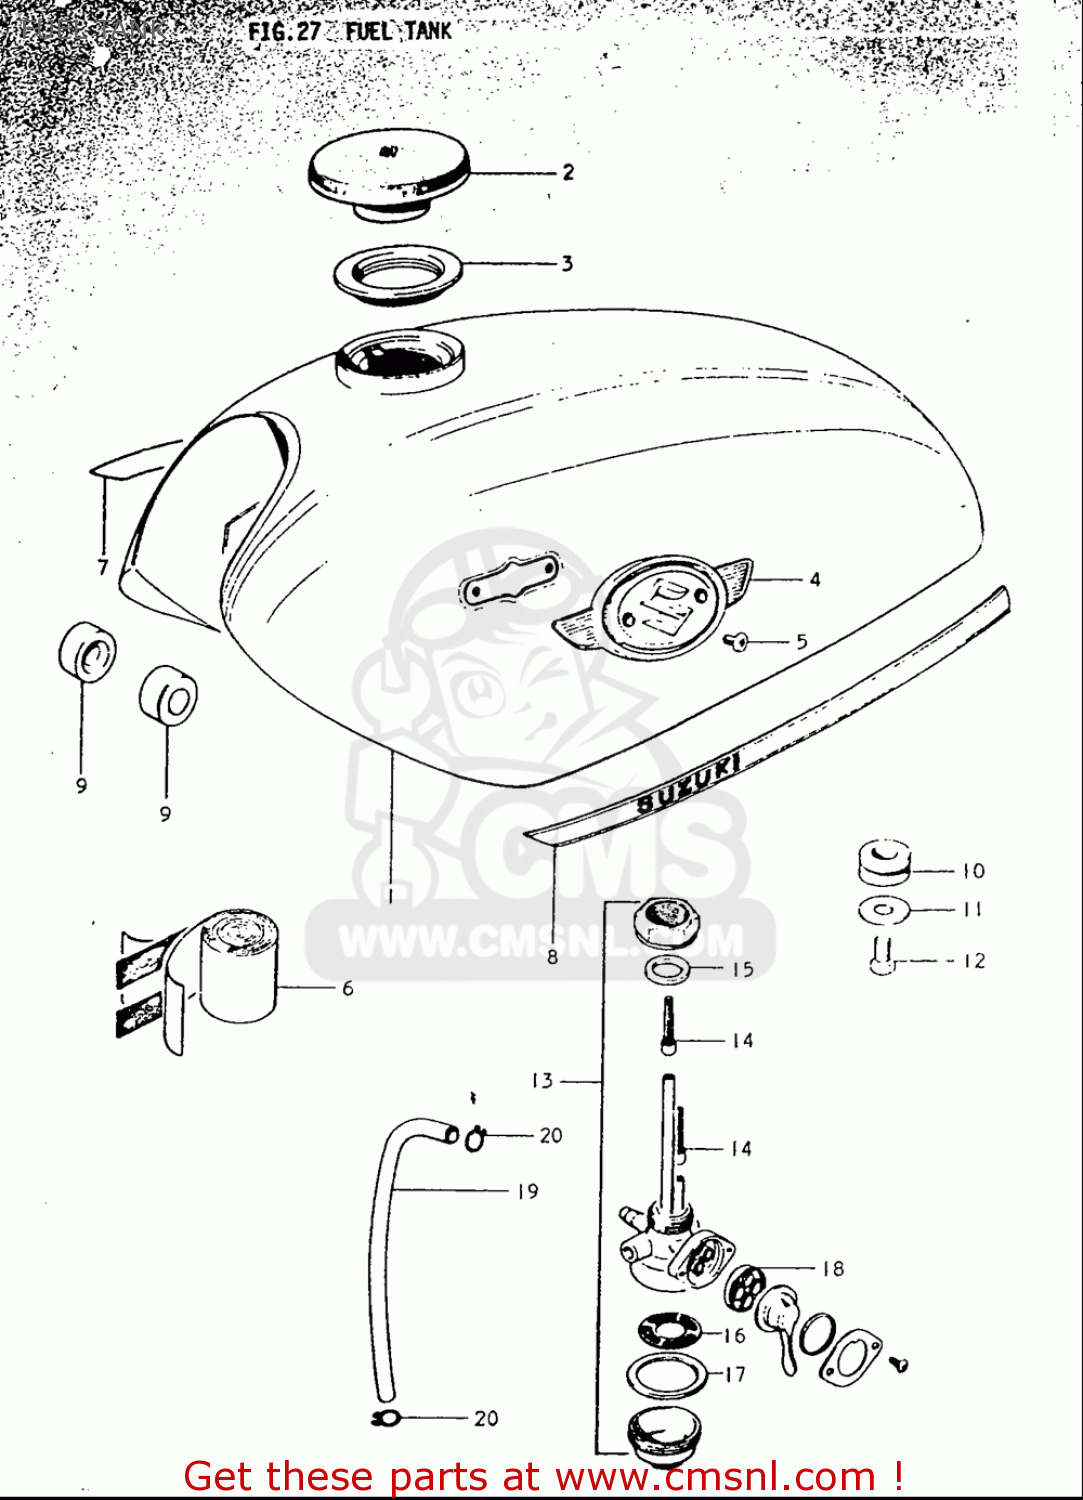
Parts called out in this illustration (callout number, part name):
9	CUSHION
11	WASHER(8.5X28X1.6)
14	FILTER SET,FUEL COCK
18	GASKET,LEVER (NAS)
19	HOSE(5X8.2X600)
